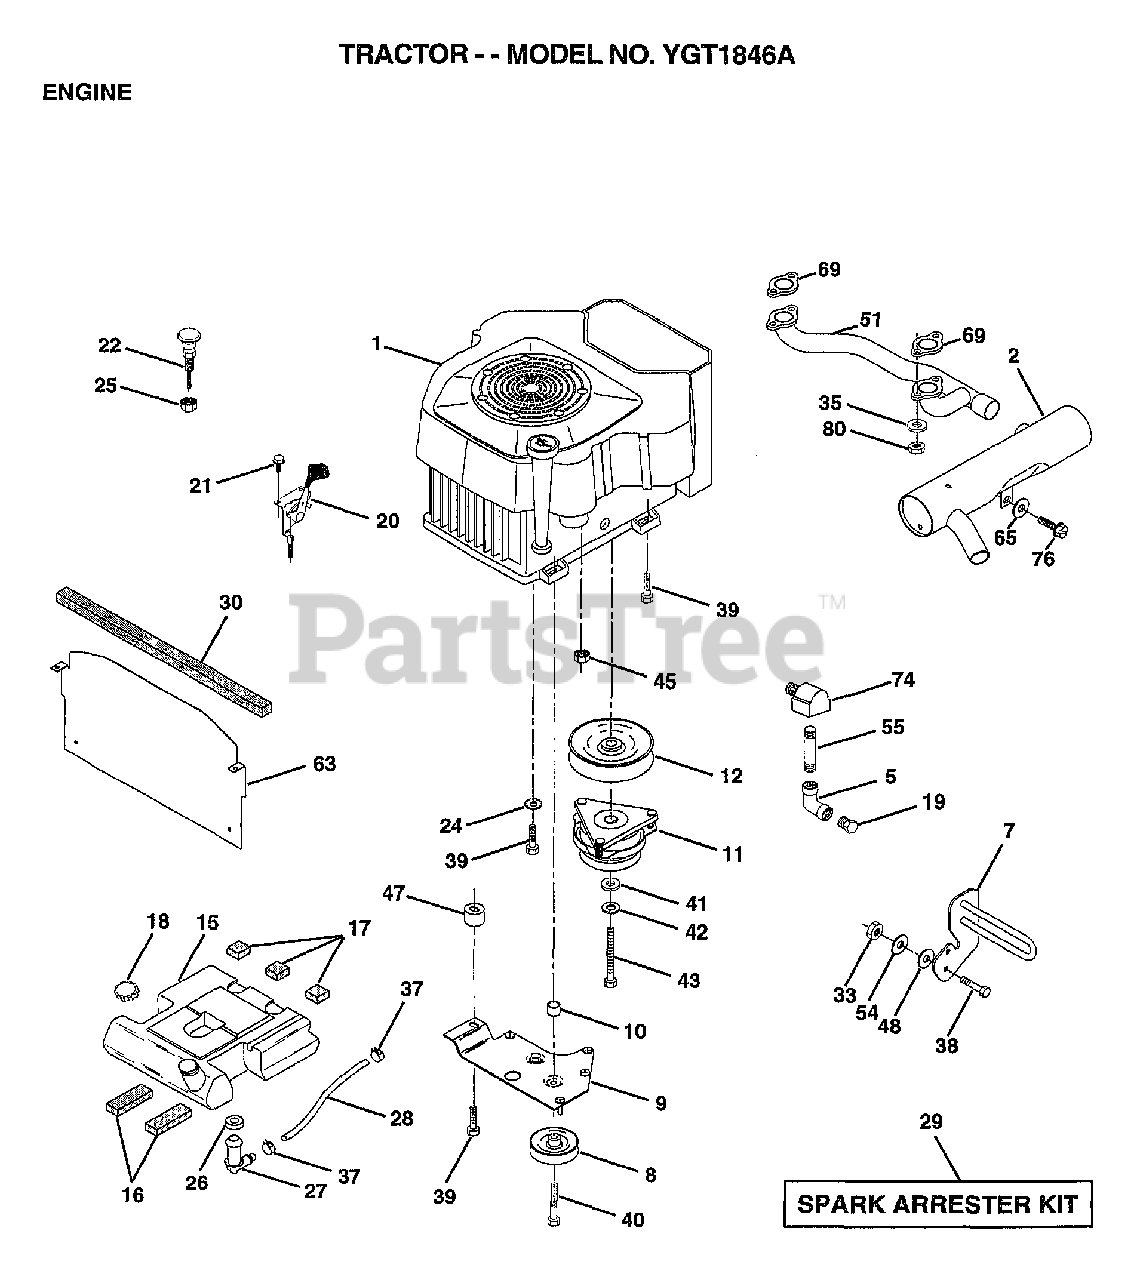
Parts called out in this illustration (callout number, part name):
2	MUFFLER SIDE1-1/8
5	ELBOW
7	GUARD.MUFFLER.ASM
9	KEEPER ASM BELT
10	BUSHING.
12	PULLEY.ENG.CLUTCH
15	TANK FUEL REAR
16	PAD IDLER TI
17	PAD-SPACER LT
18	CAP ASM FUEL
19	PLUG T
21	SCREW LT
22	CHOKE CONTROL
24	LOCKWASHER
25	"NUT,KEPS 3/8-24IM"
26	BUSHING OUTLET T
27	STEM.TANK.FUEL
29	SPARK ARREST KIT
30	FOAM-STRIP LT
33	NUT
35	WASHER.SPLIT
37	HOSE CLAMP
38	"BOLT,HEX"
39	SCREW.3/8-16X2.25
40	SCREW.TT.3/8-16X4
41	WASHER
42	LOCKWASHER
43	BOLT.7/16-20X4.25
45	NUT
47	SPACER.ENGINE
48	WASHER T
51	MANIFOLD PIPE VGT
54	WASHER
55	PIPE NIPPLE LT
63	HEAT.SHIELD.VGT.
65	WASHER
69	GASKET
74	ELBOW STREET BASS
76	SCREW
80	NUT FLANGE M8-125
